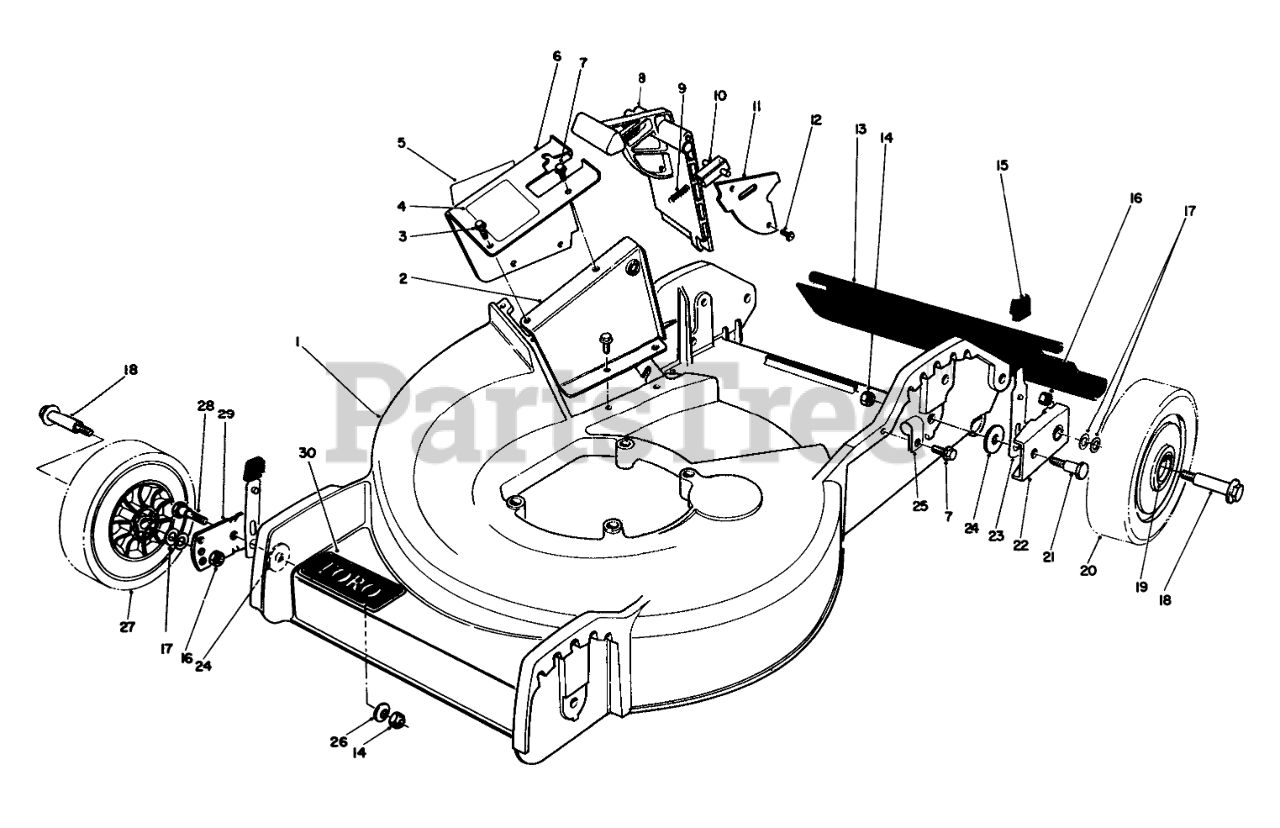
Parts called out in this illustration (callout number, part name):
1	HSG & CARTON
2	Tunnel-Inner
3	SCREW
4	DECAL - DANGER
5	DECAL-DANGER
6	Tunnel-Outer (Incl. Ref. #5)
7	SCREW
8	Door-Mulching
9	SPRING-COMPRESSION, LATCH
10	Door Latch
11	DOOR COVER
13	SHIELD - TRAILING
14	NUT-LOCK, NI
15	KNOB-ARM
16	Nut
17	WASHER
18	BOLT-WHEEL
19	BUSHING
20	Wheel & Tire Assembly (Incl. Ref. #19)
21	PIVOT SCREW
22	PIVOT ARM ASM
23	SPRING ARM ASM
24	PIVOT WASHER
25	CLAMP-NYLON
26	WASHER-BELLEVILLE
27	Wheel & Tire Assembly (Incl. Ref. #19)
28	5/16-18 PIVOT SCREW
29	PIVOT ARM ASSY
30	DECAL
